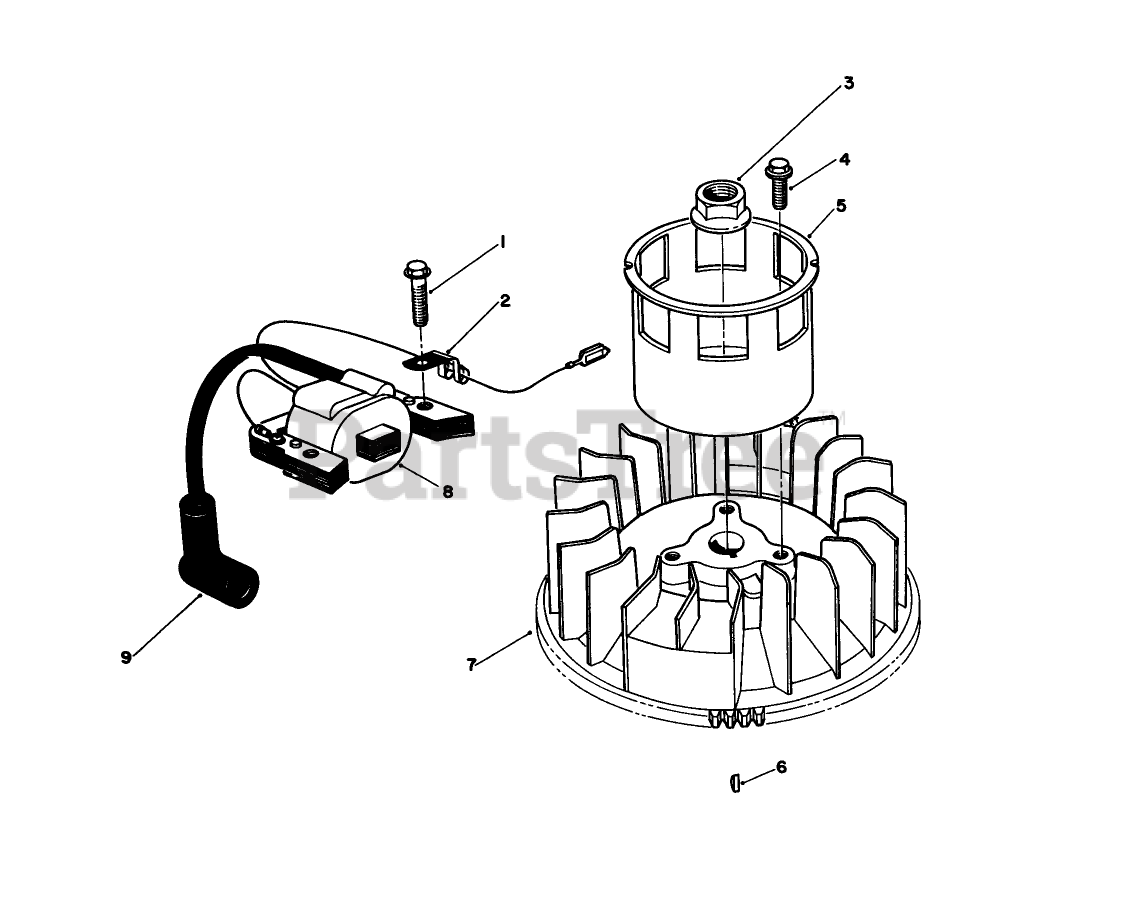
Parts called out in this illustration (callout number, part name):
2	CLAMP
7	FLYWHEEL
8	Coil Assembly-Magneto (Incl. Ref. #9)
9	COVER
